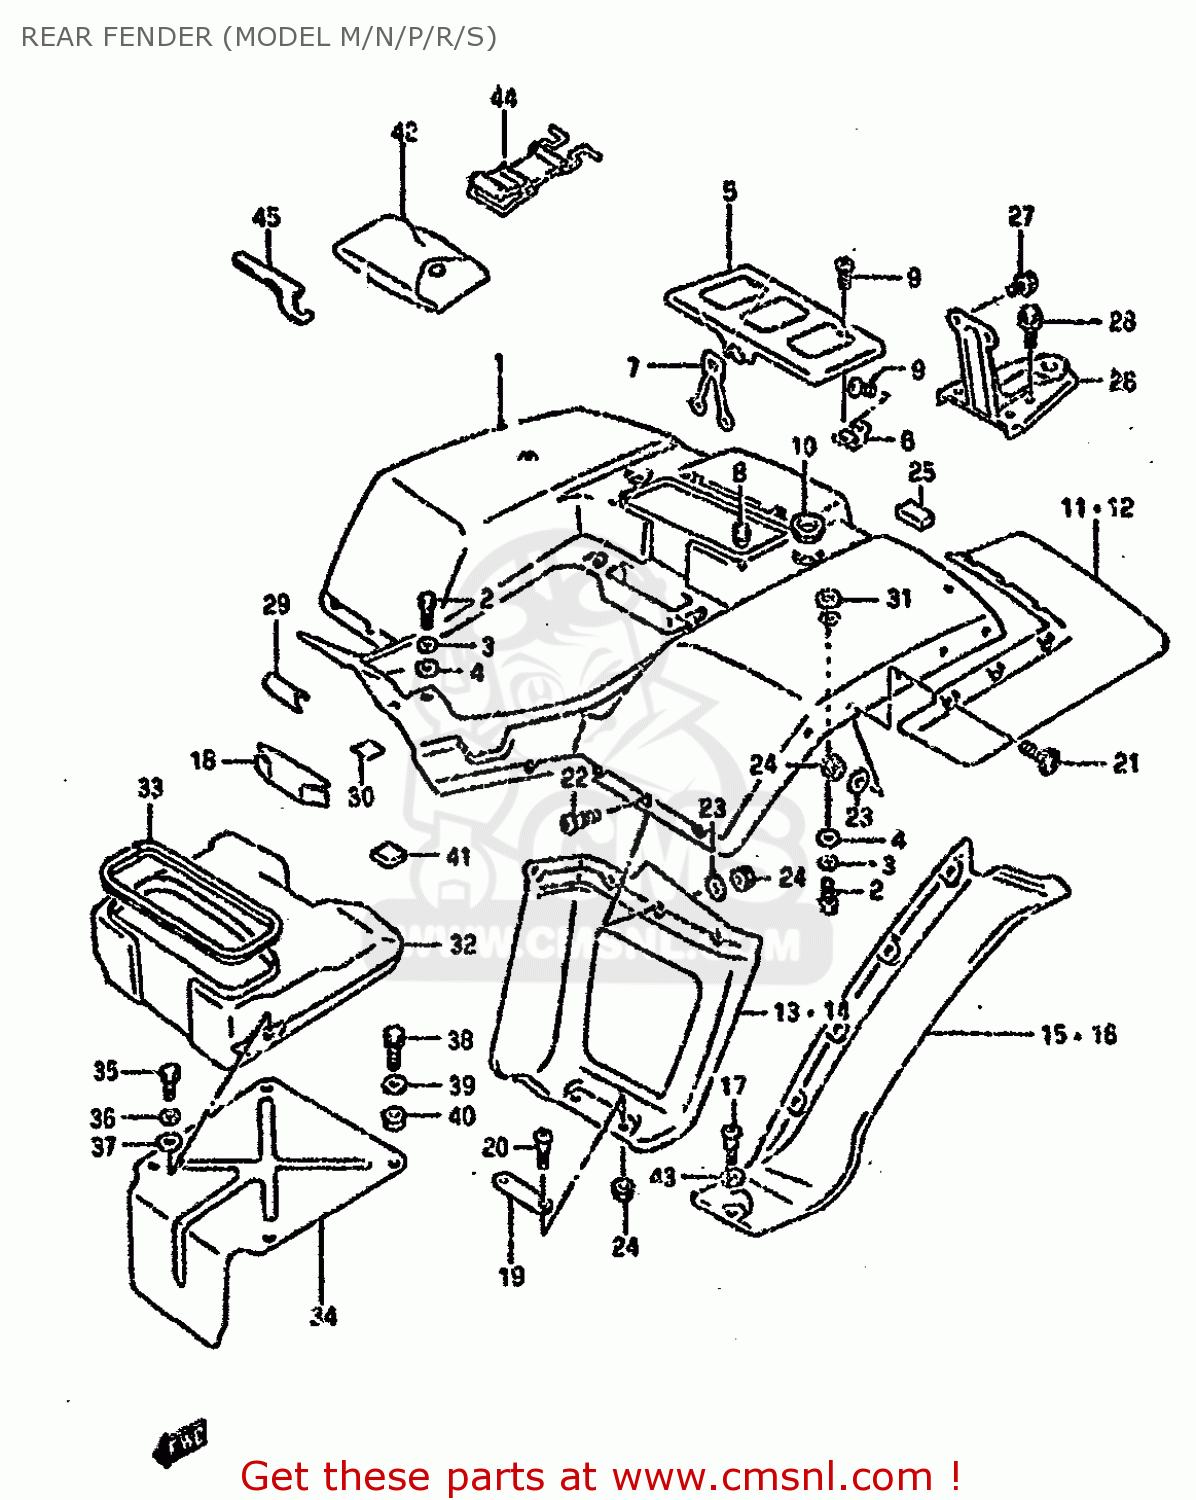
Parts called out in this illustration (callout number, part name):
1	FENDER,RR
2	BOLT
3	WASHER,LOCK
4	WASHER (6.5X24X1.6)
5	LID,RR FENDER
6	HINGE,RR FENDER LID
7	BAND,RR FENDER LID
8	CUSHION
9	SCREW
10	GROMMET
11	MUDGUARD,RR FENDER,R
12	MUDGUARD,RR FENDER,L
13	MUDGUARD,RR FENDER FR,R
14	MUDGUARD,RR FENDER FR,L
15	EXTENSION,RR FENDER MUD FR,R
16	EXTENSION,RR FENDER MUD FR,L
17	SCREW(5X15.1)
18	SHIELD,RR MUDGUARD HEAT FR
19	PLATE,MUDGUARD FR
20	SCREW(5X15.1)
21	SCREW(5X16)
22	SCREW(5X15.3)
23	WASHER (5.1X20X1.4)
24	NUT
25	CUSHION
26	BOLT
27	BOLT
28	BOLT
29	WASHER,LOCK,8.
30	TIRE
31	WASHER
32	PLUG
33	HOSE
34	HOSE(11X15X600)
35	BOLT(6X14)
36	WASHER,LOCK
37	CLIP
38	BOLT
39	WASHER
40	SCREW
41	NUT
42	TOOL ASSY
43	WASHER
44	BAND
45	CLAMP
